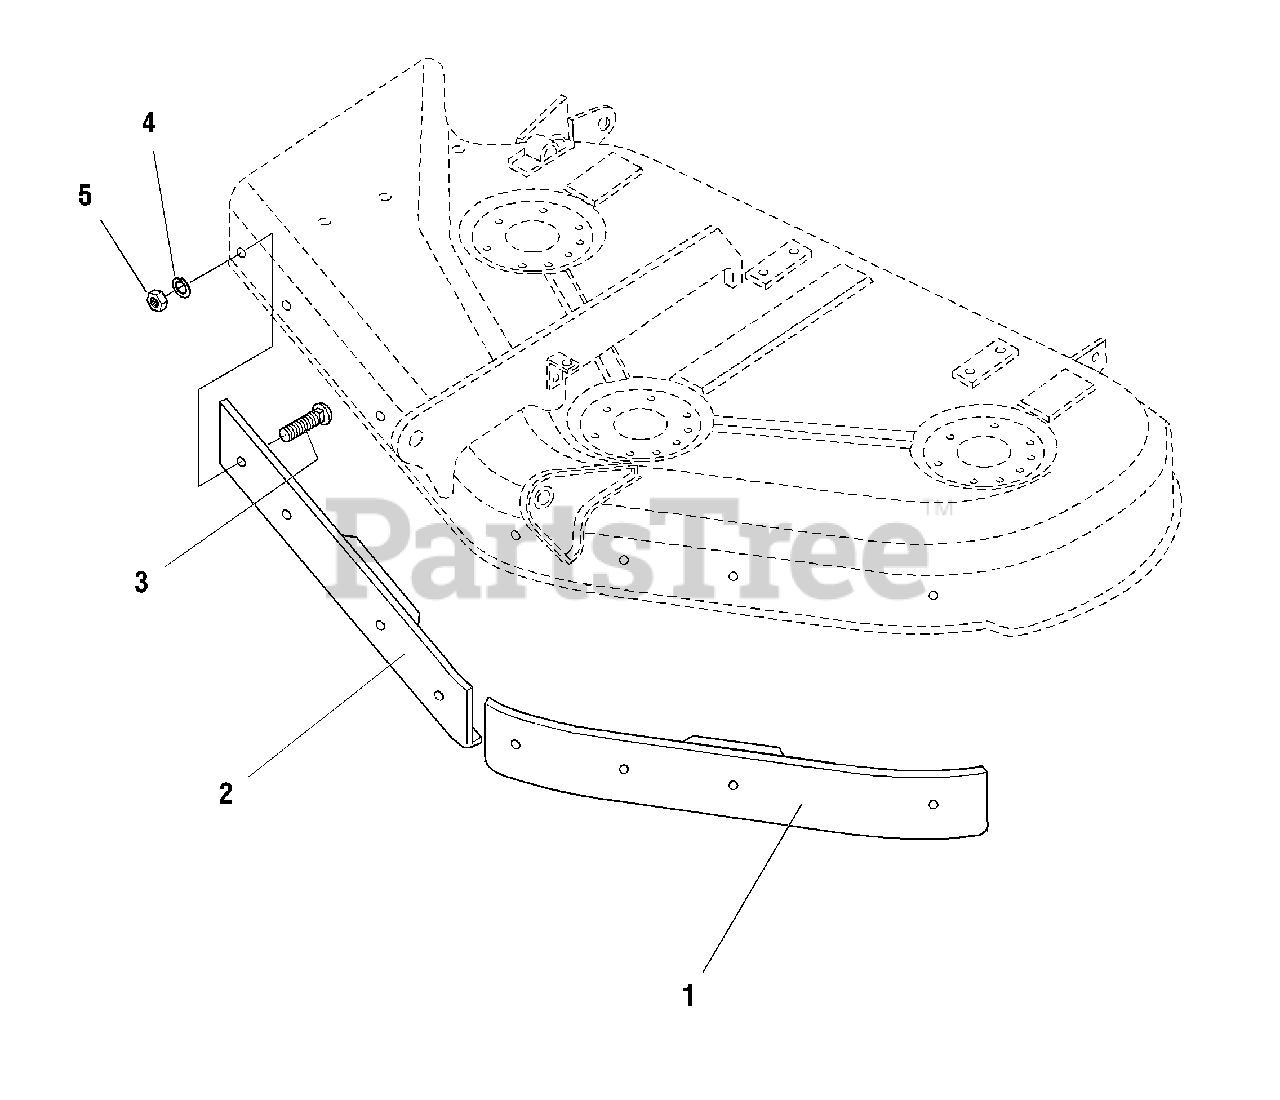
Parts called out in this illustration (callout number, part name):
1	BAFFLE, LH for 50" Mower
2	BAFFLE, RH for 50" Mower
3	CARRIAGE BOLT, 5/16-18-0.625
4	WASHER, Lock, 5/16
5	NUT, Hex, 5/16-18
